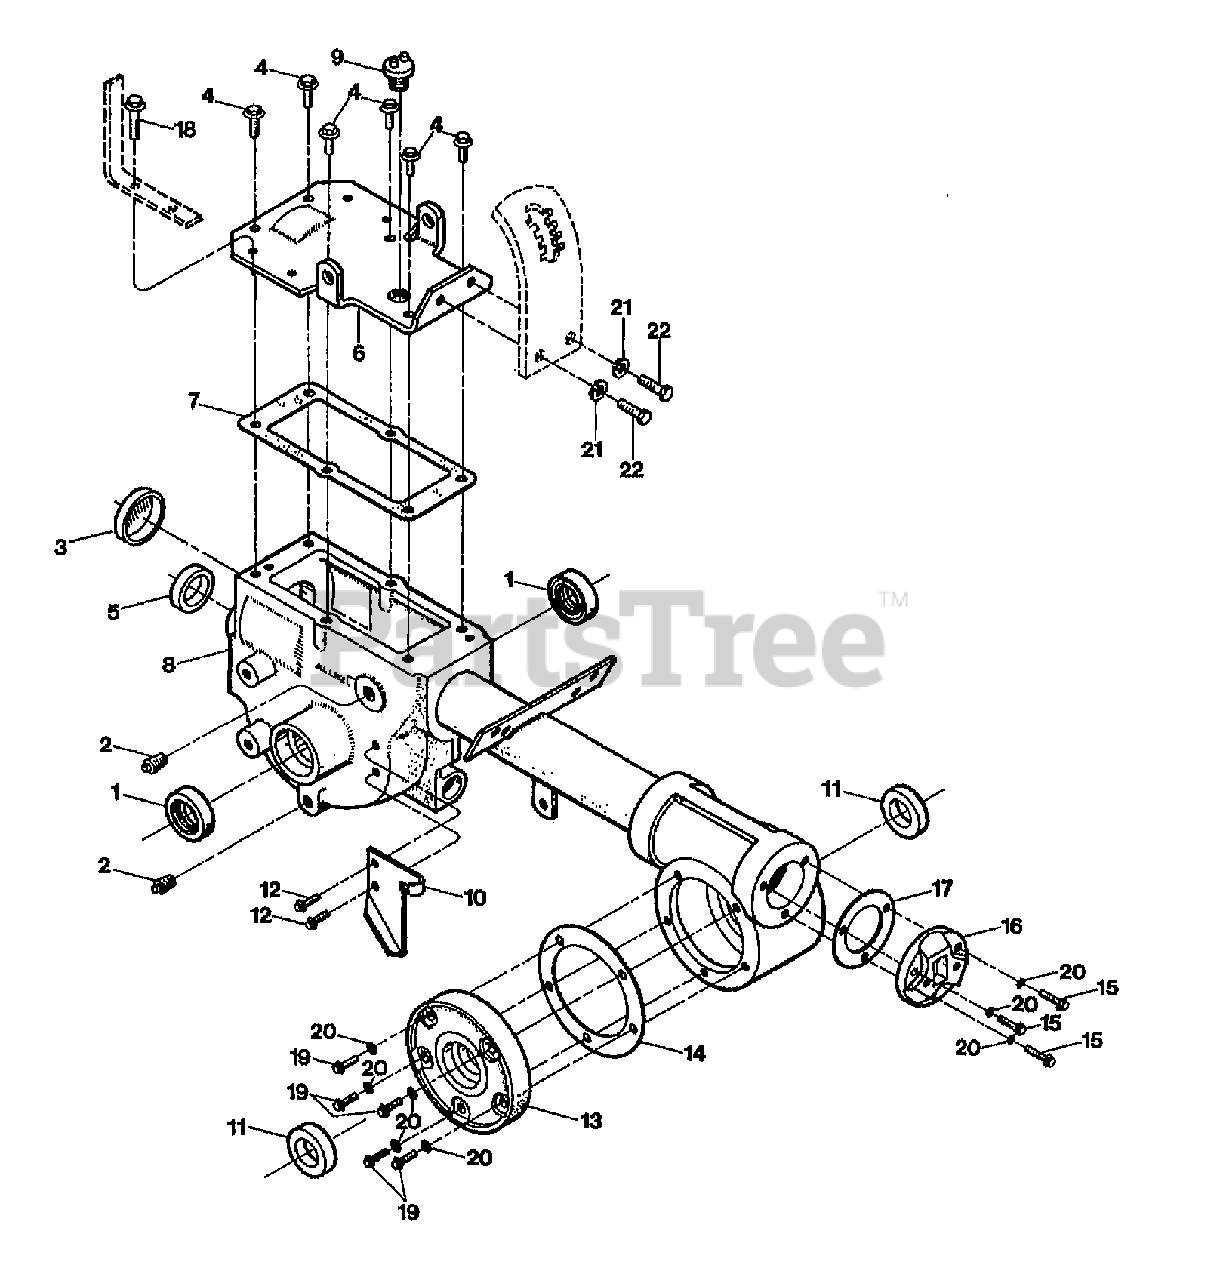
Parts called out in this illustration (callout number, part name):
1	SEAL-OIL WHEELSHAFT
2	PLUG-PIPE 1/4 NPT
3	SEAL-BORE
4	SCR-HFLK 5/16-18X.75 ZP
5	SEAL-PINION SHAFT PT/85030/00
6	KIT-COVER TRANS W/HDW (INCL. FOUR OF 18, TWO EACH OF 21, 22)
7	GASKET-TRANS COVER
8	ASSM-TRANS A-UNIT P/ECHO
9	PLUG-OIL FILL 3/4-10
10	PLATE-CABLE MT PNT
11	SEAL-TILLER SHAFT
12	SCR-HFLK 5/16-18X.62 G5ZP
13	COVER-TILLER HSG MACH (INCL. FIVE SCREWS,#19)
14	GASKET-TILLER COVER (FITS ALL COVERS)
15	SCR-HFLK 1/4-20X.875
16	CAP-REAR #1115
17	GASKET-BRG COVER
18	SCR-HFLK 5/16-18X1.00 ZP
19	SCR-HH 1/4-20X.625
20	WASHERS, NYLON. NOT REUSEABLE
21	WASHER-LK .375 @ DEPL
22	SCR-HH 3/8-16X.75 G5 ZP
